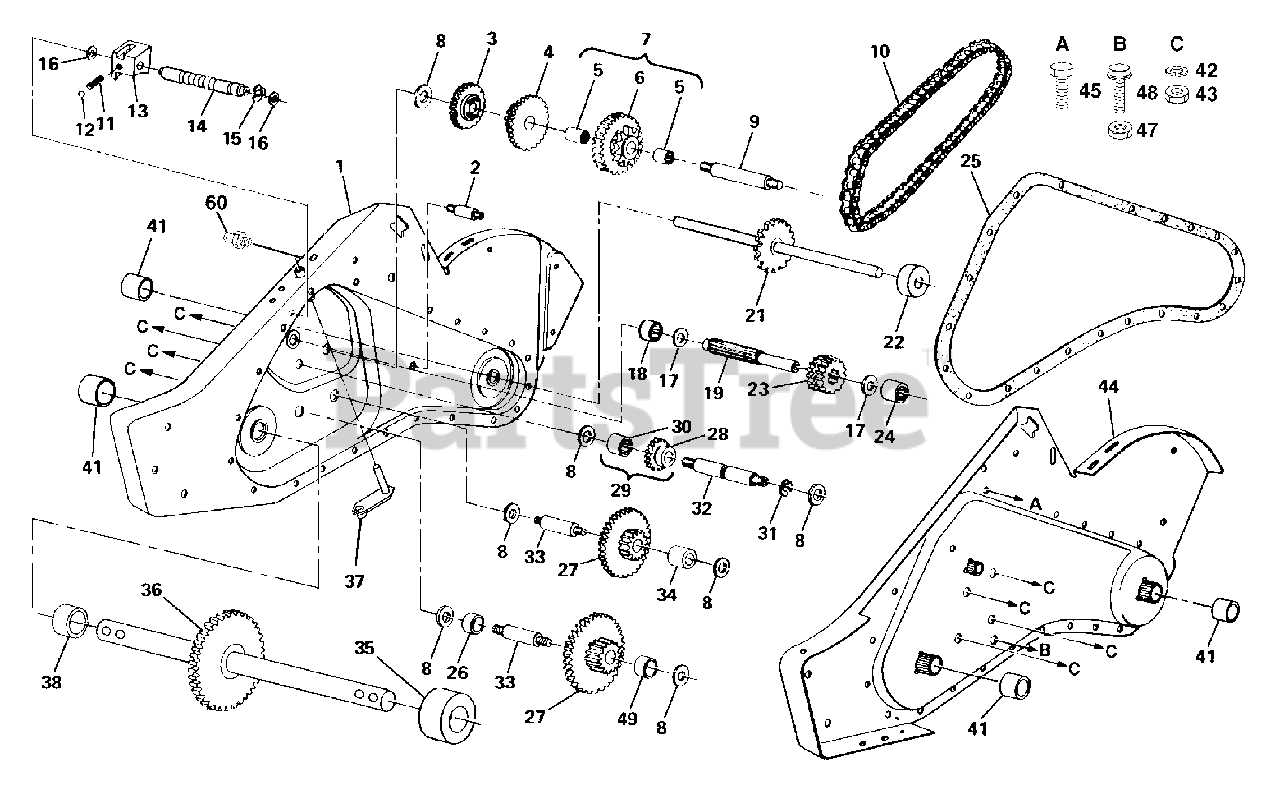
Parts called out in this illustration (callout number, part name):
1	Gearcase Assembly, R.H., with Bearing
2	Bolt, Upset
3	Gear, Reverse
4	Gear, Cluster, Red., 1st and 2nd
5	Bearing, Needle
6	Sprocket Assembly, Tine
7	Sprocket Assembly with Bearings
8	Washer
9	Shaft, Reduction, 1st
10	Chain, Roller, 60P
11	Spring, Shift, Fork
12	Ball, Steel
13	Fork, Shift
14	Shaft, Shift
15	Klip Ring
16	Washer, Seal
17	Race, Bearing, Thrust, 5/8 I.D.
18	Bearing, Needle
19	Shaft, Input
21	Shaft Assembly, Tine
22	Spacer 1.008 x 1-3/4 x .645
23	Pinion, Input
24	Bearing, Needle
25	Gasket, Gearcase
26	Spacer .765 I.D. x 1.12 x 5/8
27	Gear, Cluster, Red., 2nd and 3rd
28	Gear, Reverse Idler
29	Gear Assembly, Reverse Idler
30	Bearing, Needle
31	Klip Ring
32	Shaft, Reverse Idler
33	Shaft, Reduction, 2nd
34	Spacer .765 I.D. x 1-1/8 x 1-3/8
35	Spacer, Ground Drive, L.H.
36	Shaft Assembly, Ground
37	Arm Assembly, Shift
38	Spacer, Ground Drive, R.H.
41	Seal Asm Oil
42	Washer, Lock 7/16
43	Nut, Hex 7/16-20
44	Gearcase Assembly, L.H., with Bearing
45	Screw, Thd Cut 5/16-18 x 5/8
47	Nut, Hex Head 5/16-18
48	Screw, Whiz-Lock 5/16-18 x 4
49	Spacer .765 I.D. x 1.12 x 3/4
60	Fitting Grease
60	Grease, Plastilub Number 1
